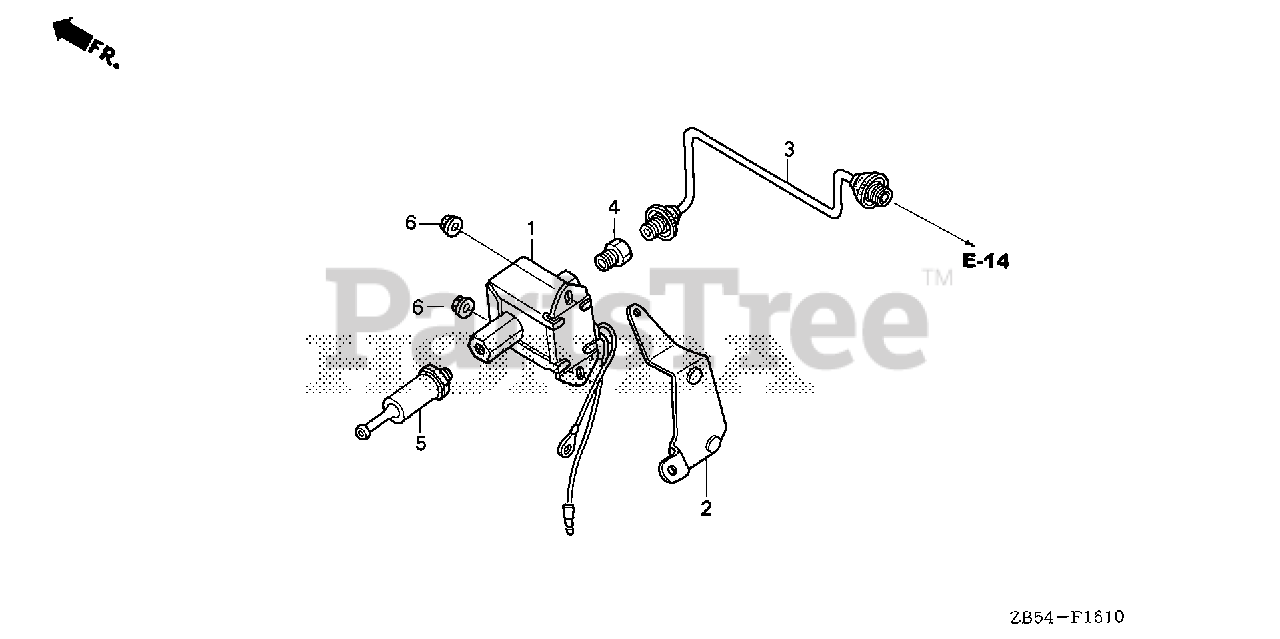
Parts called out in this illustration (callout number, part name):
1	PUMP ASSY., FUEL (MSDS)
2	STAY, FUEL PUMP *NH105* (MAT BLACK)
3	PIPE, FUEL
4	NUT, JOINT
5	FILTER, FUEL LINE
6	NUT, FLANGE (6MM)
